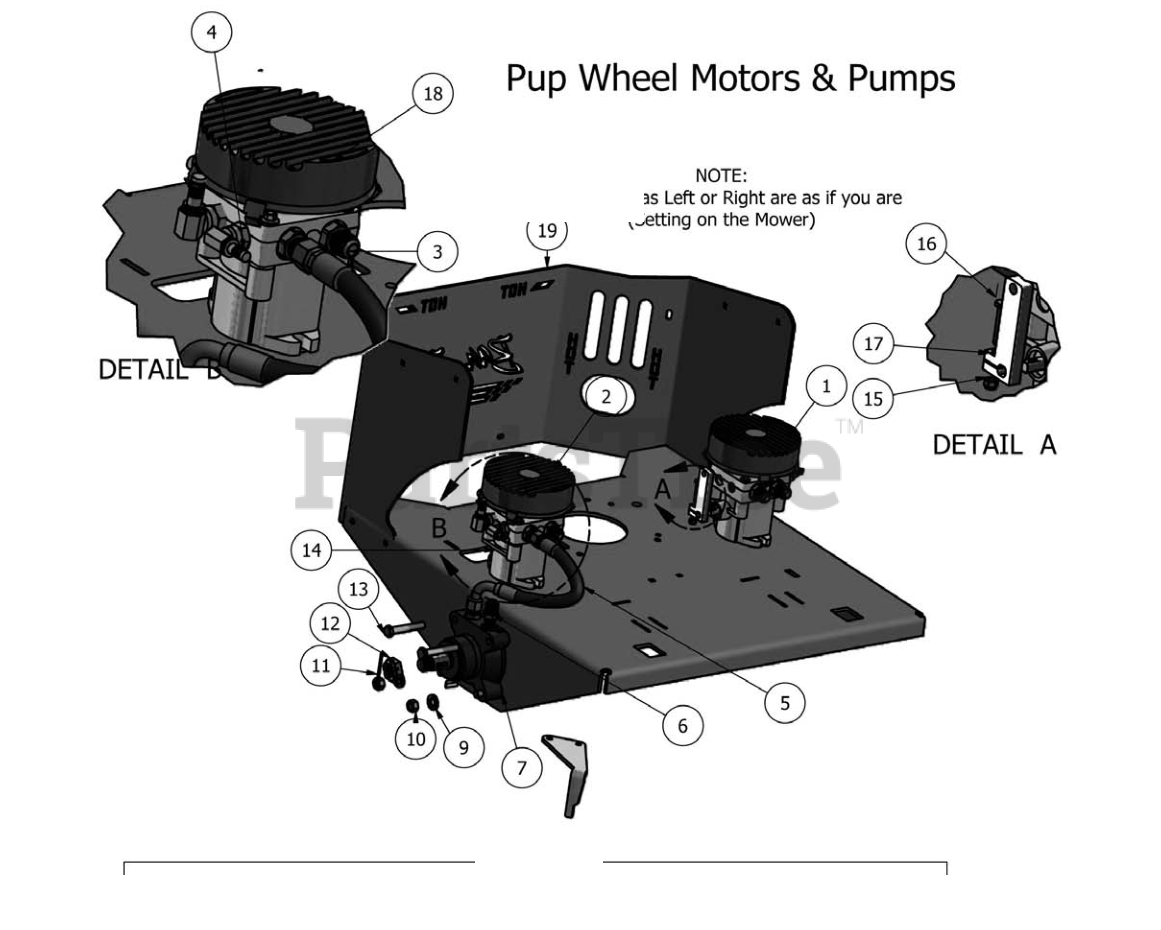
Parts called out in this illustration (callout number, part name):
1	Left Hydraulic Pump
3	Hydraulic Fitting
4	3/8" x 9/16" Male Fitting
5	16" Hydraulic Hose
6	Hydrauilc Fitting (Wheel Motor)
7	15cc Parker Wheel Motor Right
8	15cc Parker Wheel Motor Left
9	1/2" Lock Washer
10	1/2" Hex Nut
11	1/8" x 2 1/4" Cotter Pin
12	Castle Nut
13	1/2" 3" hex Bolt
14	Right Hydraulic Pump
15	1/4" Nylock Nut
16	1/4" x 1 1/2" Bolt
19	Pup Rear Plate
